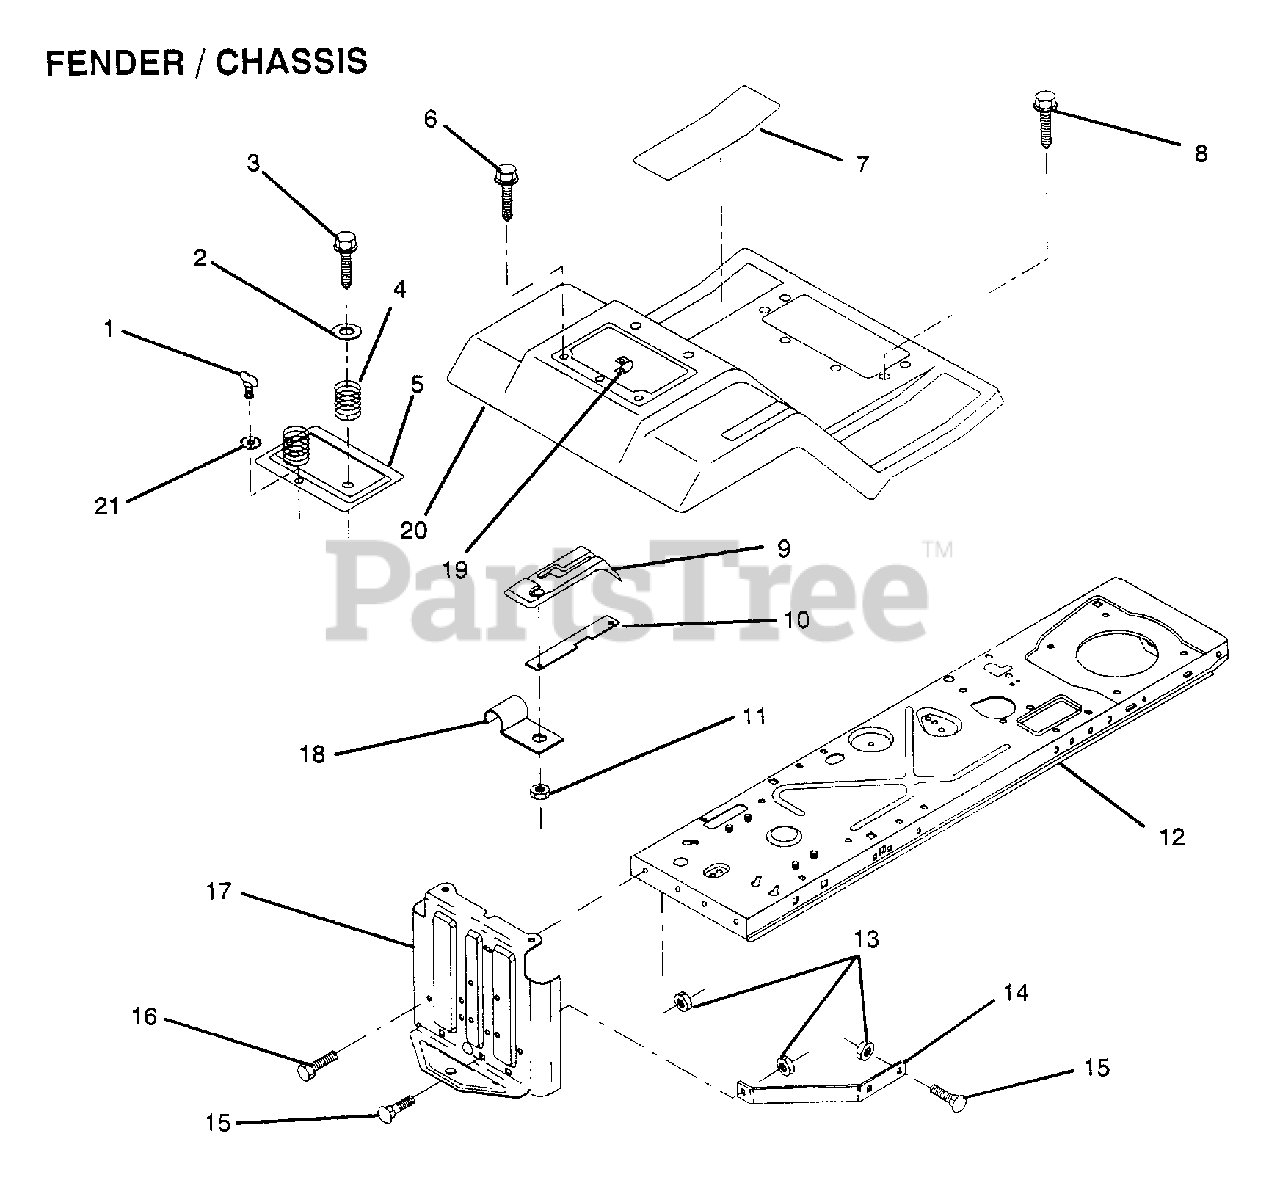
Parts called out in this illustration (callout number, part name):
1	STUD.1/4.TURN
2	WASHER
3	SCREW
4	SPRING COMPRESSIO
6	SCREW LT
8	SCREW
9	CONSOLE SHFT 5SP
10	"SHIFT LOCK, BAR"
11	NUT
12	FRAME ASS'Y
14	"BRACE,DRAWBAR "
15	BOLT
16	BOLT
17	DRAWBAR
18	"CLIP,INSULATOR"
19	RECEPTACLE LT
20	"FENDER,FOOTREST"
21	RETAINER LT
